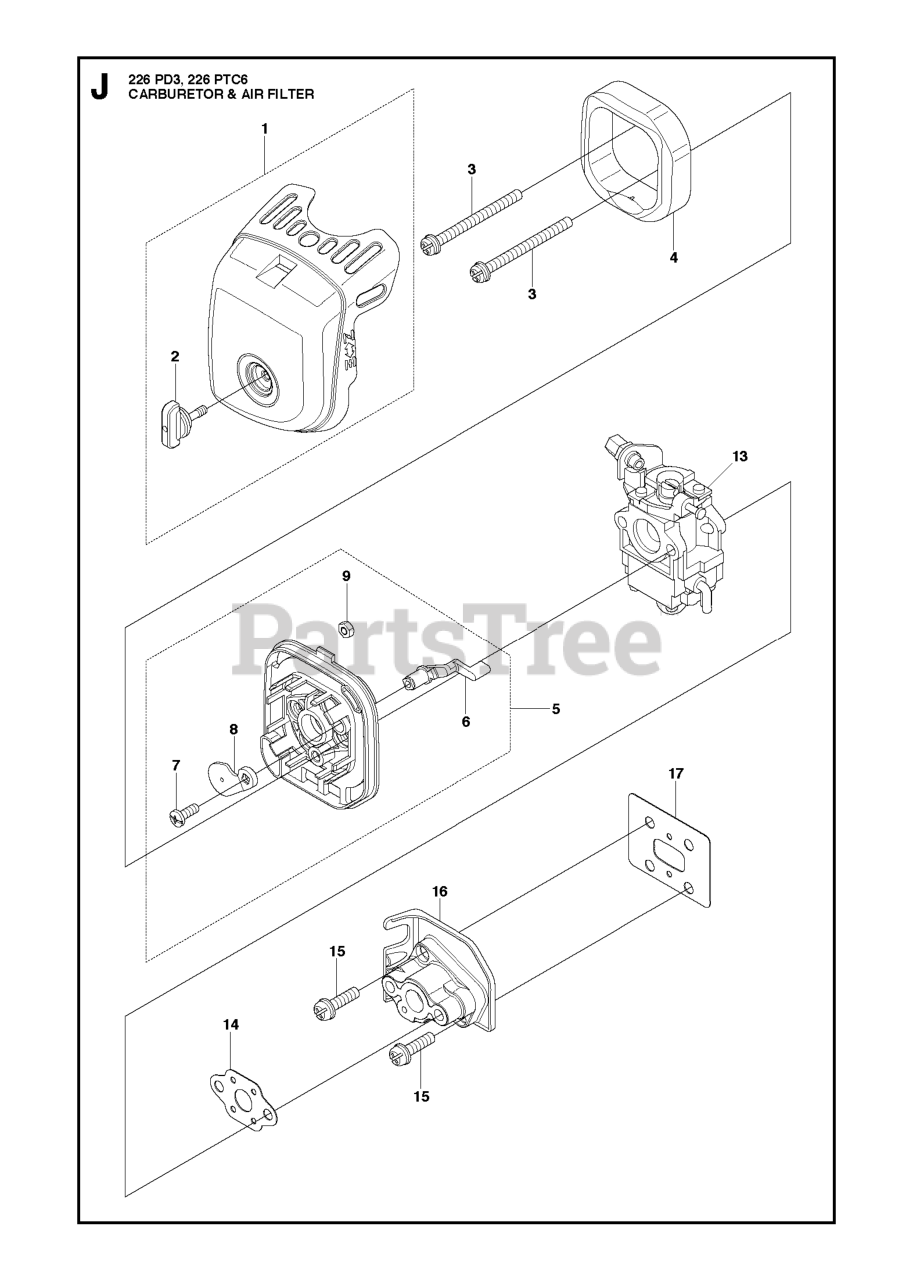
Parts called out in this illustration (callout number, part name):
7	SCREW
8	PLATE.CHOKE
13	CARBURETOR ASSEMBLY
